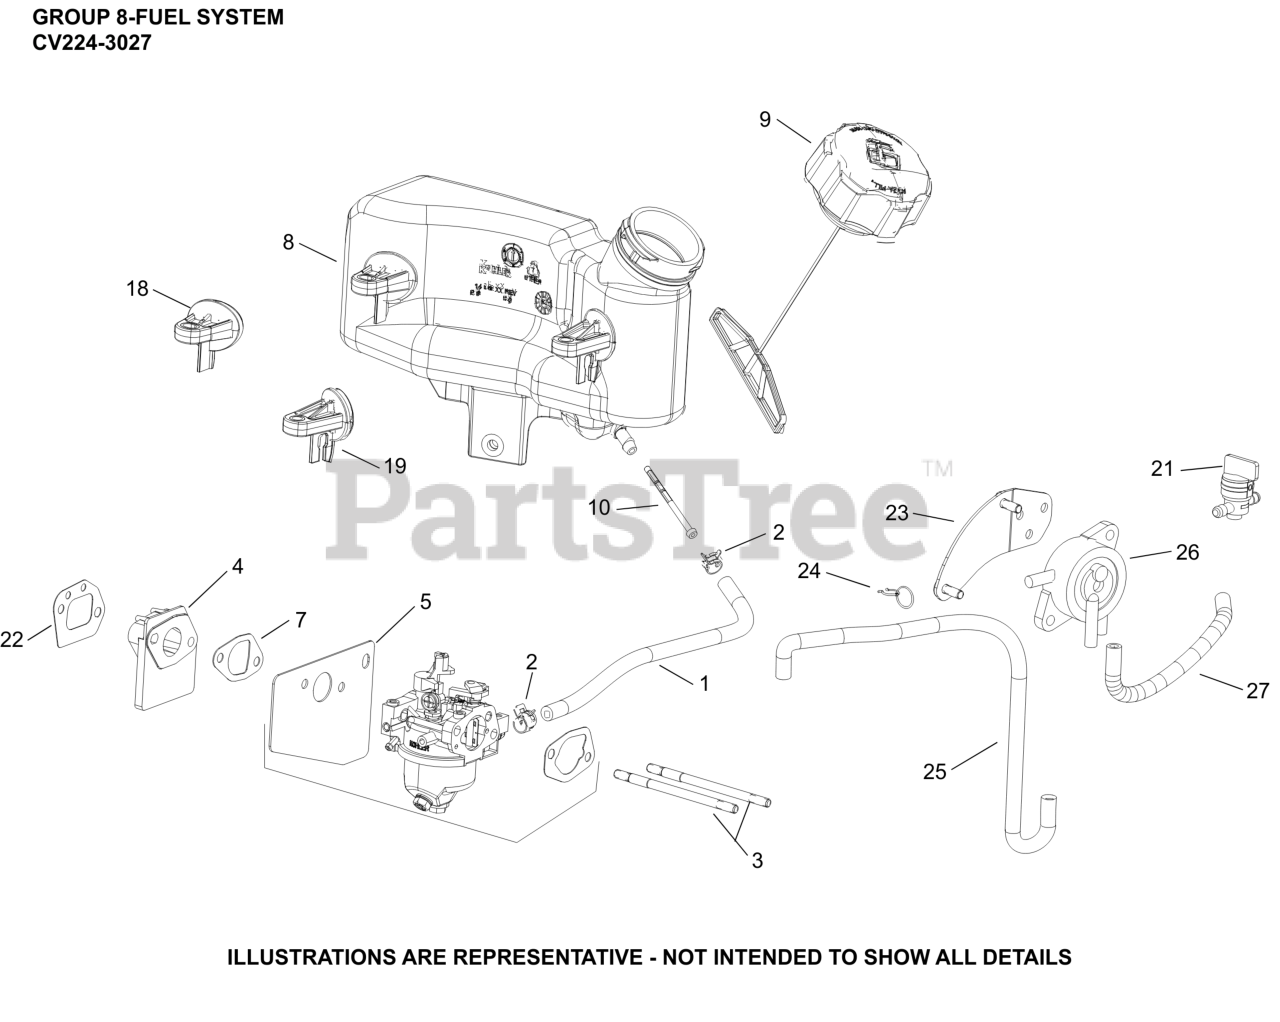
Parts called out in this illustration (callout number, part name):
1	HOSE, FUEL LOW-PERMEATION (CKY)
2	CLAMP, HOSE (NON-CALIF)(#1423710S)
3	STUD,M6X1.0X100.2MM
4	KIT, SPACER
5	KIT, CARBURETOR HEAT SHIELD GASKET
7	KIT, INTAKE GASKET
8	TANK, FUEL
9	FUEL CAP ASSEMBLY
10	FILTER, FUEL IN-NIPPLE
18	BRACKET, FUEL TANK
19	BRACKET, FUEL TANK
21	VALVE, FUEL SHUTOFF ASSEMBLY
NI	GASKET SPACER
NI	BRACKET, PURSE PUMP
NI	CLAMP, HOSE
NI	HOSE, VACUUM
NI	KIT,HIGH AL(4000-8000 FT)USE 14 755 04-S
NI	KIT, CARBURETOR REPAIR (RUIXING)
NI	KIT, CARBURETOR COMPLETE
NI	PUMP, FUEL
NI	HOSE, FUEL LOW-PERMEATION
